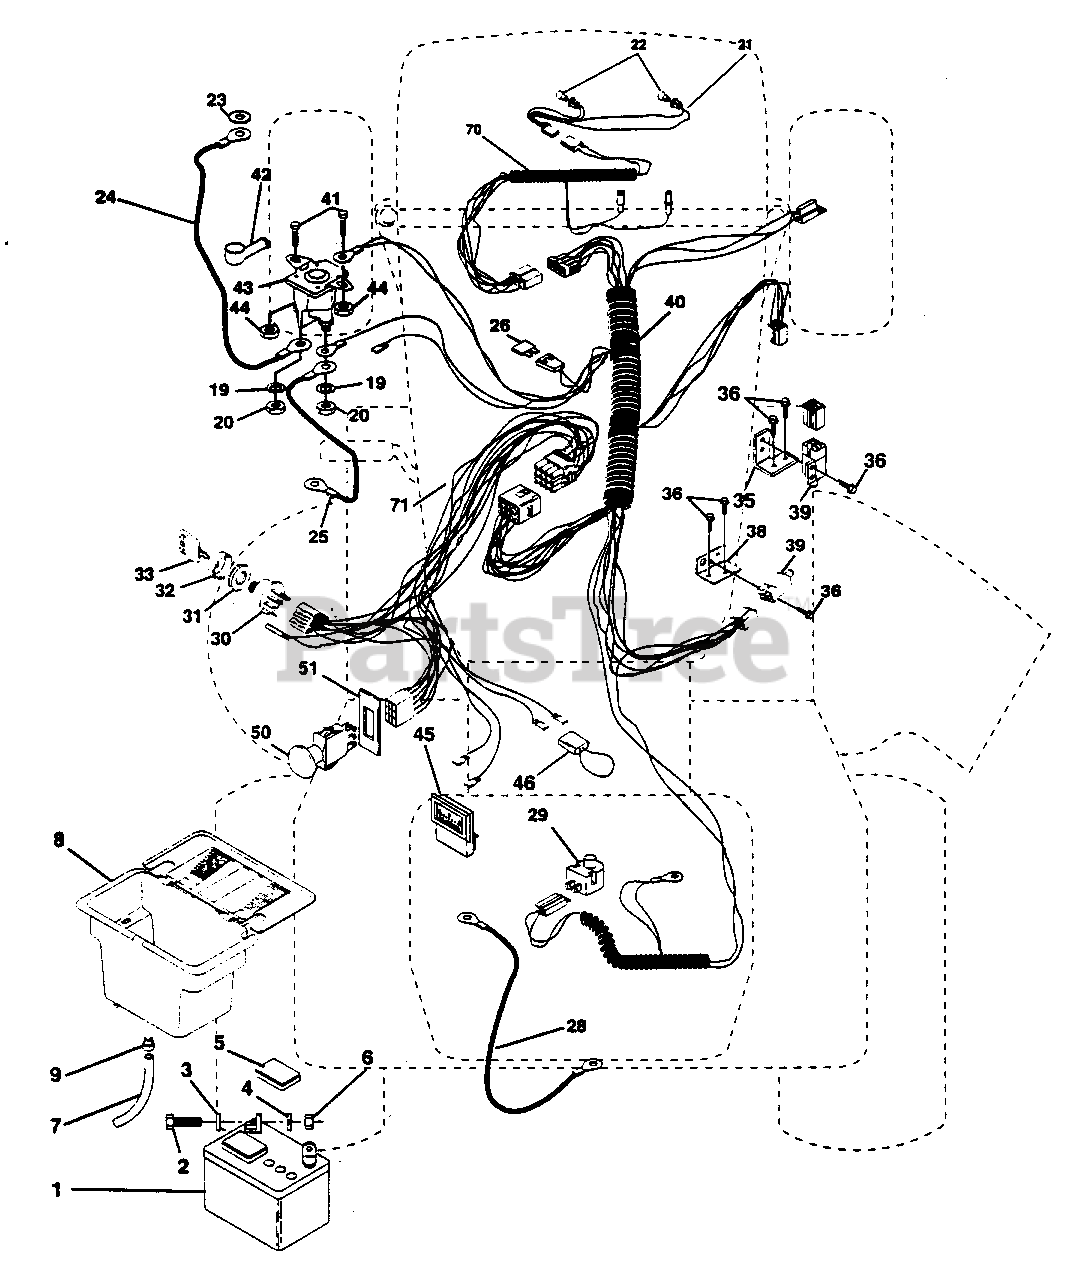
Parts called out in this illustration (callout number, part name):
1	Battery 12 Volt 25 Amp (AYP part number)
2	Bolt Hex Hd 1/4-20unc X 3/4 (AYP part number)
3	Washer 9/32 X 5/8 X 16 Ga (AYP part number)
4	Washer Lock Hvy Helical 1/4 (AYP part number)
5	Caps Battery 20/25/30 AMP (AYP part number)
6	Nut Fin Hex 1/4-20 Unc (AYP part number)
7	Tube Plastic 20" (AYP part number)
8	Battery Case Hng Mech (AYP part number)
9	Clamp Hose Olive (AYP part number)
19	Washer Lock 1/4 (AYP part number)
20	Nut Jam Hex 1/4-20 Unc (AYP part number)
23	Washer Lock Internal Tooth 1/4 (AYP part number)
24	Cable Battery 6 Ga 11"red (AYP part number)
25	Cable Battery 6 Ga 43"red (AYP part number)
26	Fuse 30 AMP Auto Green (AYP part number)
28	Cable Ground 6 Ga 12"black (AYP part number)
29	Switch Plunger Nc Gray (AYP part number)
30	Switch Ign 4 Pos. (AYP part number)
31	Nut Ignition (AYP part number)
32	Cover Sw Key Blk 1 25 Text SLT (AYP part number)
33	Key Ign (AYP part number)
36	Screw Tap Hex #10-24unc X 1/2 (AYP part number)
38	Bracket Switch Interlock (AYP part number)
39	Switch Intlk Clutch Gry 4 Term (AYP part number)
40	Harness Ign Lt Mech Dash (AYP part number)
41	Bolt Fin Hex 1/4-20 x 1/2 (AYP part number)
42	Cover Terminal Red (AYP part number)
43	Solenoid (AYP part number)
44	Nut Keps Hex 1/4-20 Unc (AYP part number)
45	Ammeter rectangular (AYP part number)
46	Protection Wire Loop (Hourmeter)
50	Switch PTO 3 pdt. delta (AYP part number)
51	Ring Retainer PTO (AYP part number)
70	Harness Eng. B&S
71	Harness Dash Lt Private Label (AYP part number)
